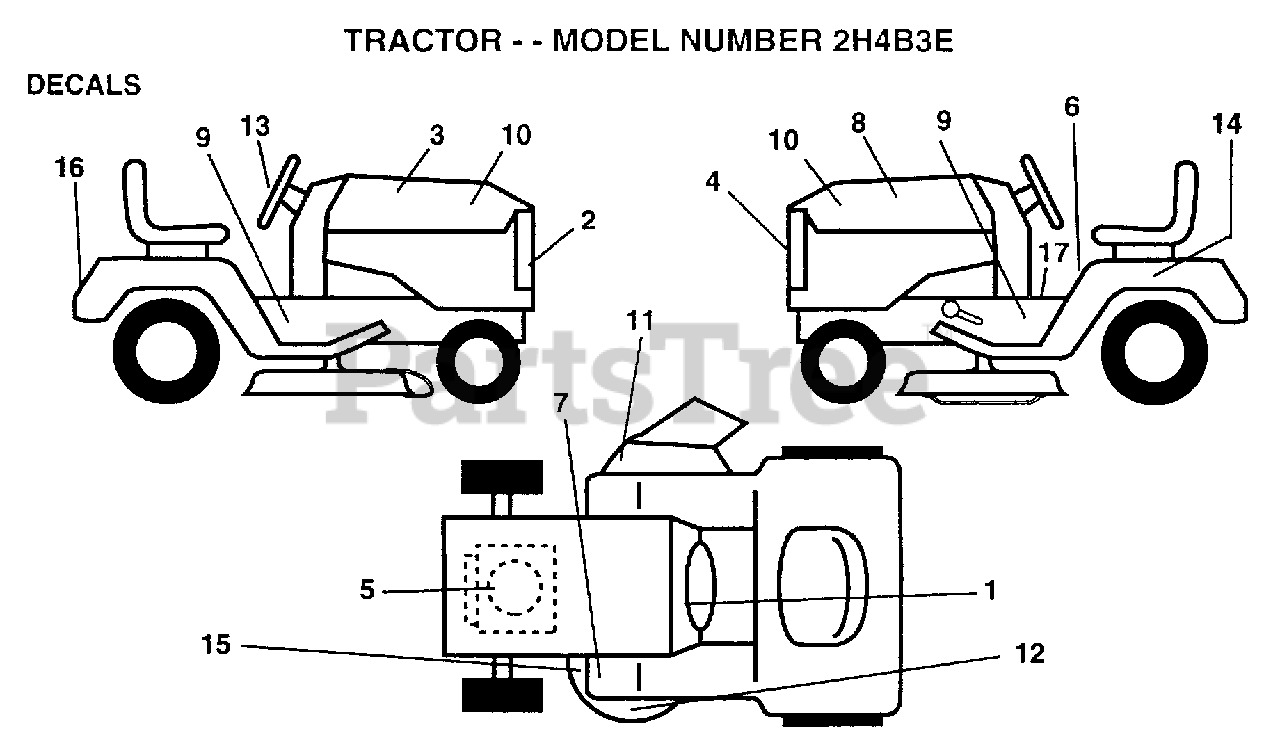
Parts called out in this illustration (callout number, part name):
1	DECAL.DASH.INSTR.
2	GRILL DECAL
3	DECAL HOOD RH RLY
5	DECAL, HP ENGINE
6	DECAL CAUTION
7	DECAL T
8	DECAL HOOD LH RLY
9	CHASSIS DECAL
11	"DECAL, WARNING"
13	"DECAL,STR WHL"
14	DECAL.BTRY.DANGER
15	DECAL
16	FENDER DECAL
17	DECAL BRAK PARK
